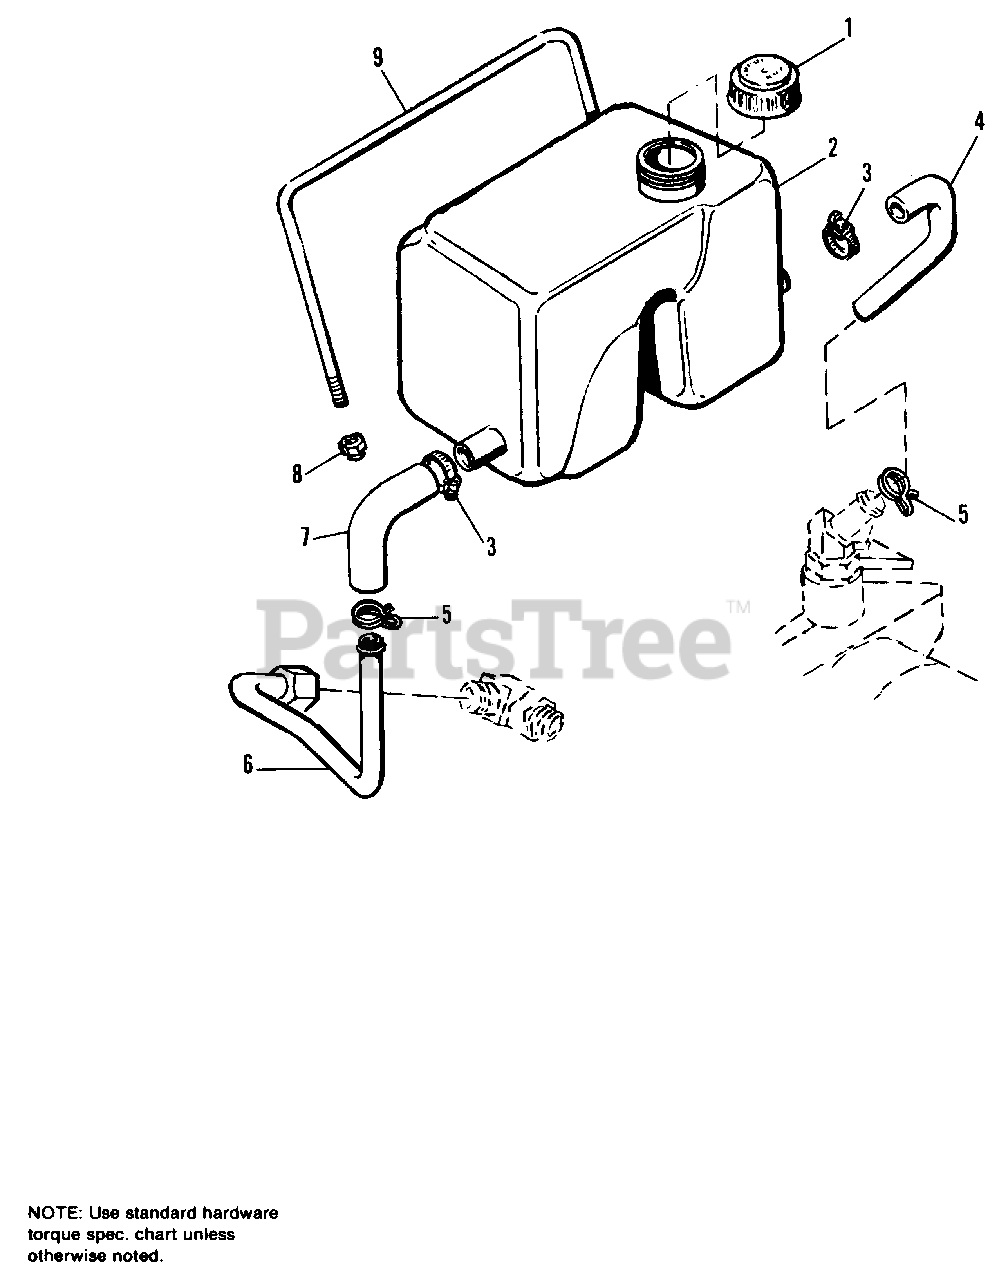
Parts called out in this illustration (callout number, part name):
1	CAP, Reservoir
2	RESERVOIR (1 Gal.)
3	CLAMP, Hose, #10
4	HOSE, Hydraulic
5	CLAMP, Hose
6	LINE, Hydraulic, Steel
7	HOSE, Hydraulic
8	NUT, Hex, 1/4-20
9	ROD, Reservoir Mtg.
